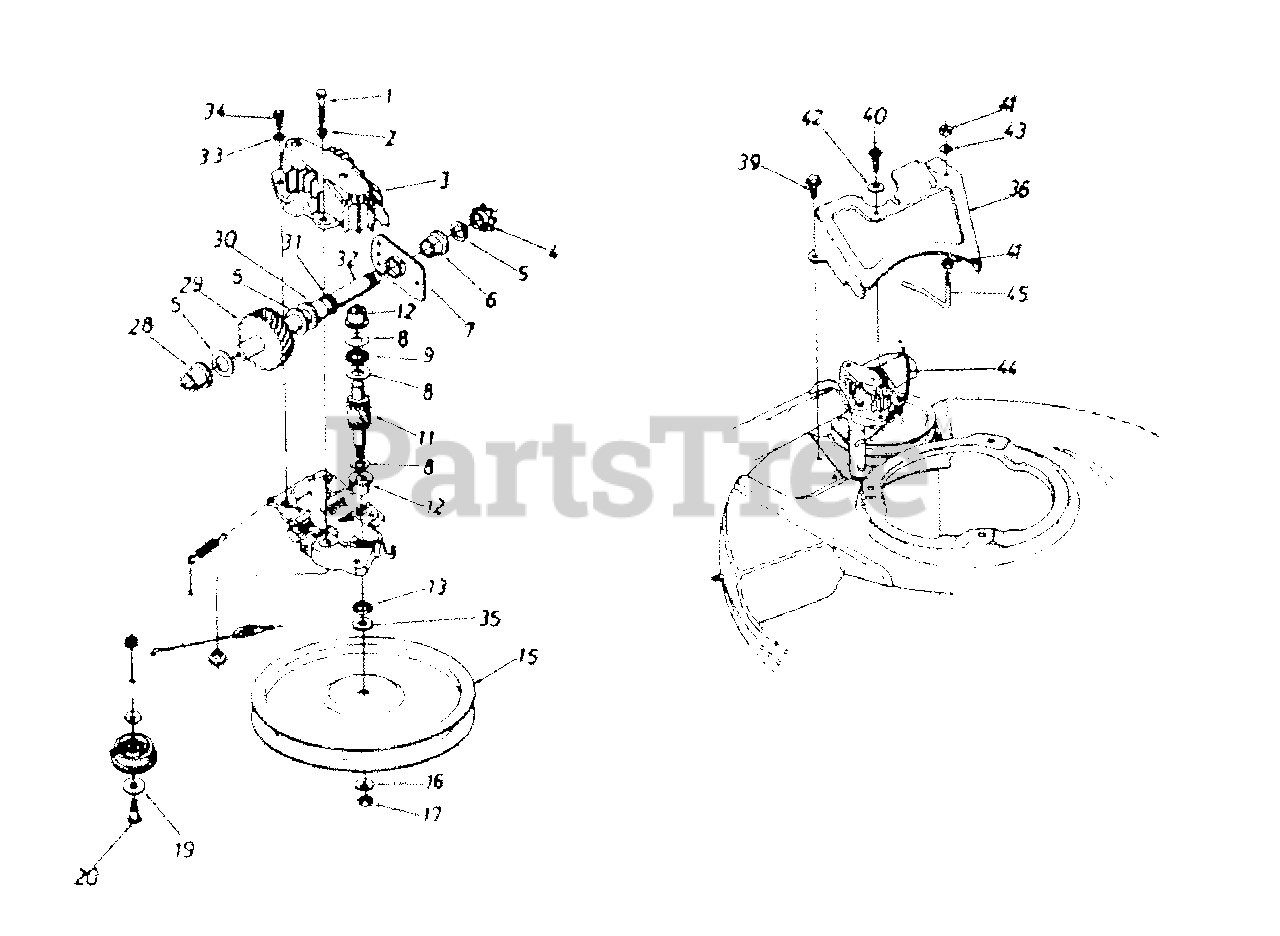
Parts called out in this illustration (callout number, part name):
1	Hex Bolt w/Patch 1/4-20 x 1.25"
2	L-Washer 1/4" ID
3	Upper Housing Half
4	#48 Sprocket 7 Tooth x 1/2 Pitch
5	Flat Washer 5/8" ID x.030 OD
6	Hex Flange Bearing .631" ID
8	Thrust Washer .382" ID x .70" OD
9	Thrust Bearing .375" ID x .812" OD
11	11 Tooth Helical Gear
12	Flange Bearing
13	Oil Seal
15	Pulley 5.06" ID
16	Bell Washer .265" ID x .75" OD
17	Hex Nut 1/4-28 LH Thread
19	Flat Washer .390" ID x 1.0" OD
20	Shoulder Bolt .375" x .40"
28	Flange Bearing .56"
29	33 Tooth Helical Gear
30	Flange Bearing .629"
31	Oil Seal .625"
32	Gear Sprocket Shaft
33	Lock Washer #10
34	Hex Tap Screw #10 x .62"
35	Hex Washer .26" x .88"
40	Hex Tap Screw 1/4 x .62"
41	Hex Nut 1/4-20
42	Bell Washer .265" ID x .75"
43	Lock Washer 1/4" ID
44	SP Cable - 48"
45	SP Belt Guard
